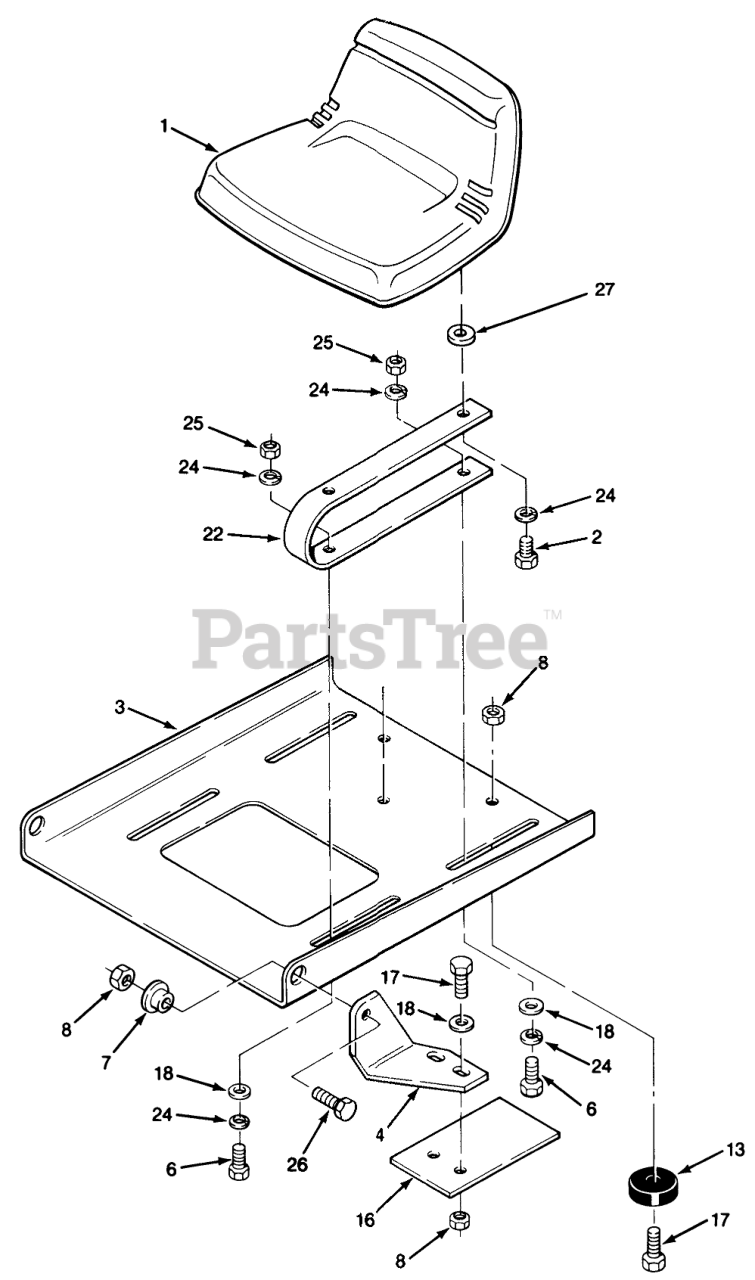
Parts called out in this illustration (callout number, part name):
1	SEAT V-410
2	SCREW-HH
3	PLATE-SEAT PIVOT B
4	BRACKET-PIVOT L.H B
6	SCREW-HH
7	BUSHING
8	NUT-LOCK, NI
13	BUMPER
16	PLATE R
17	SCREW-HH
18	WASHER-PLAIN
22	SPRING-SEAT B
24	WASHER-LOCK
25	NUT-HEX
26	SCREW-HH
27	SPACER-NYLON
